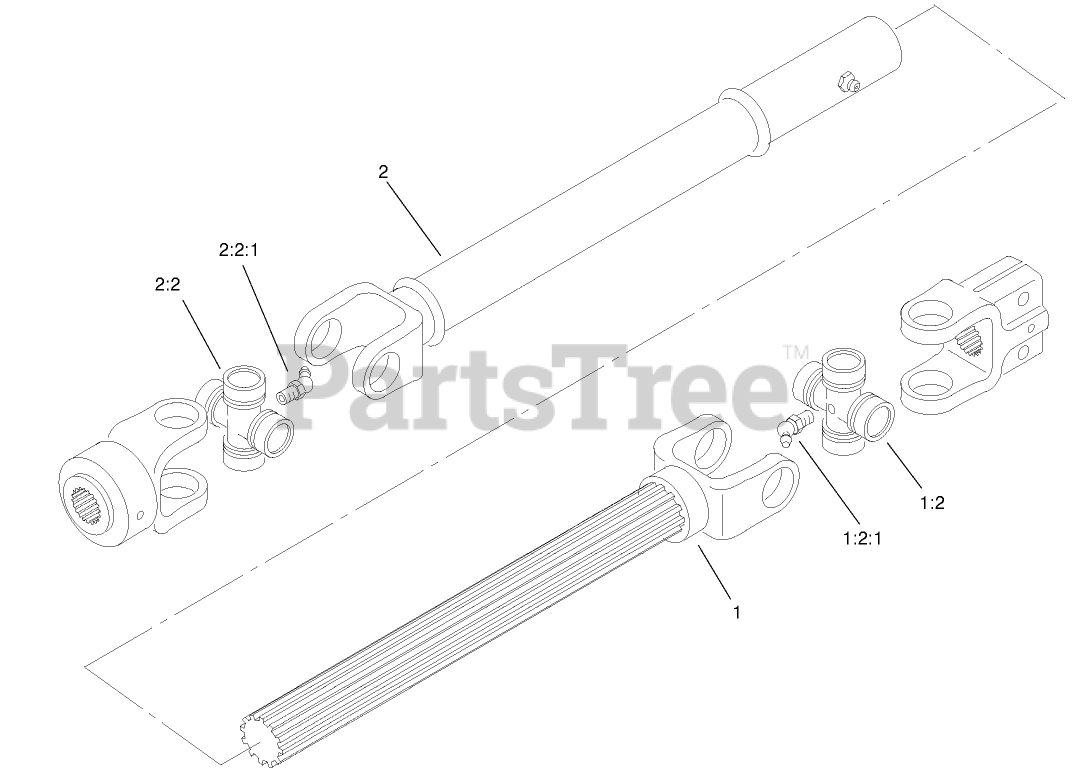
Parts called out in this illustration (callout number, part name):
1	JOINT AND SHAFT HALF ASM
1:2	U-JOINT KIT
2	JOINT AND TUBE HALF ASM
2:2	U-JOINT KIT
